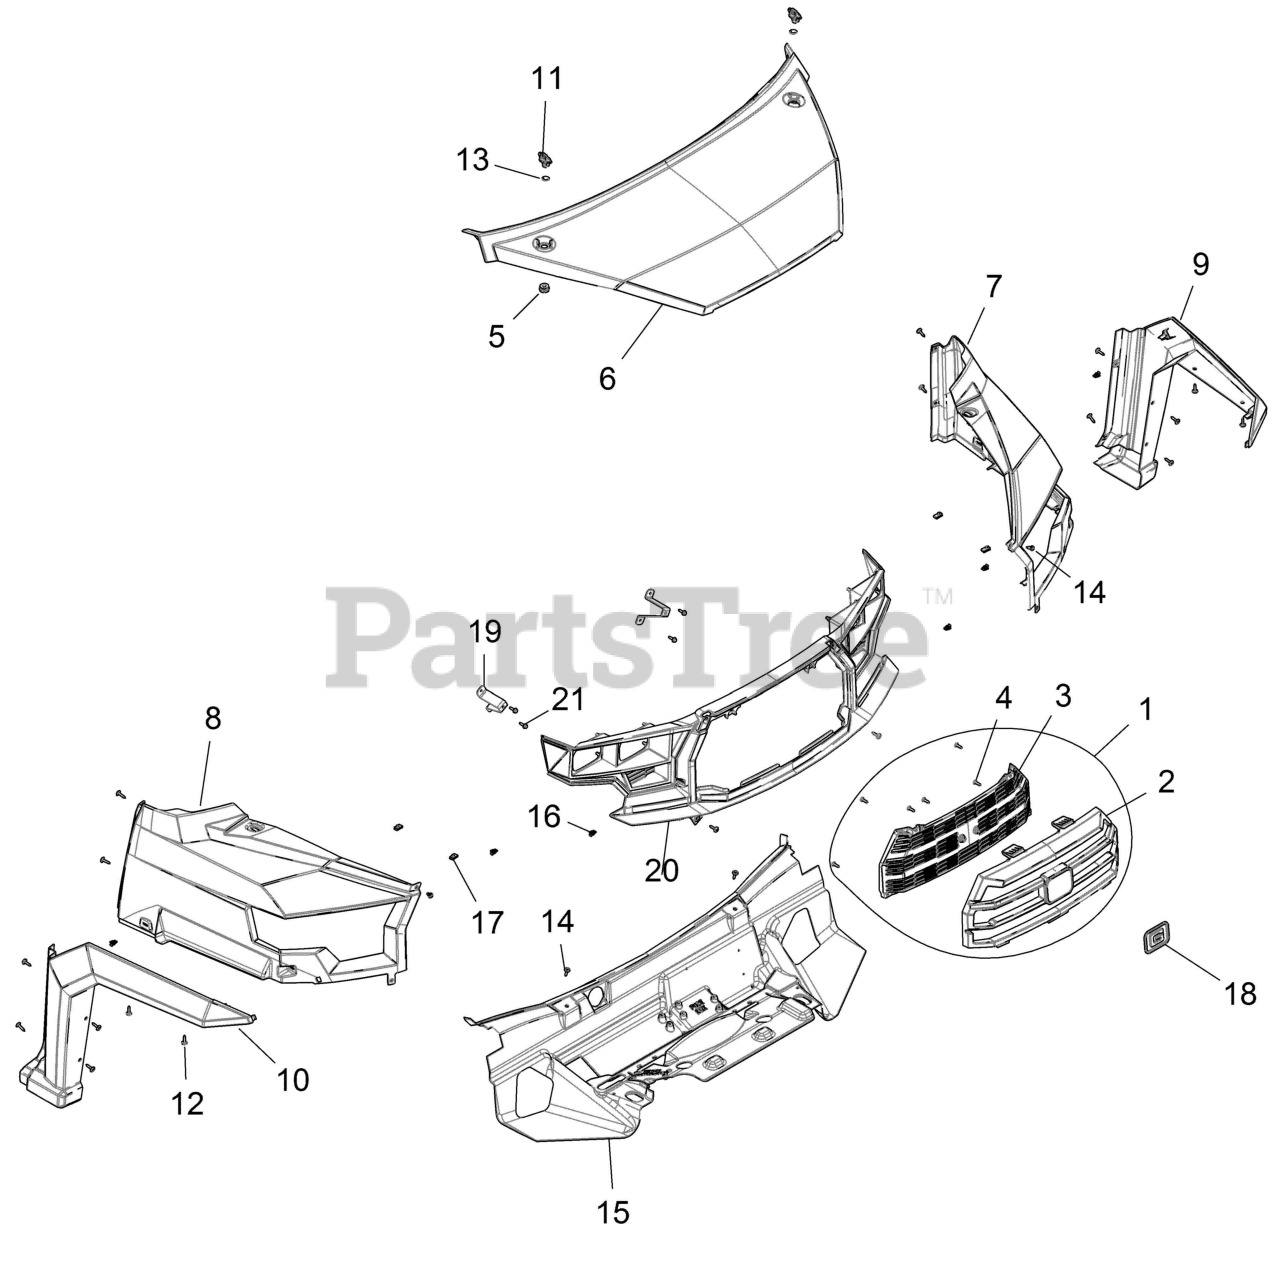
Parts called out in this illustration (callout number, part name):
1	ASM., GRILL, GRAVELY
2	GRILL, FRONT, UPPER, BLACK
3	GRILL, UPPER, TRIM
4	SCR-TXPH-#14 X .75 HI-LO RIE
5	GROMMET-LATCH
6	HOOD-ARIENS,INDY RED
7	FENDER-FRONT,LH,ARIENS,I RED
8	FENDER-FRONT,RH,ARIENS,I RED
9	FLARE, FENDER, FRONT LH
10	FLARE, FENDER, FRONT RH
11	LATCH, 1/4 TURN
12	SCR-TXTH-M6X1.0X25 RIE
14	RIVET-TUFLOK,.315-.325X.787 (5
15	LINER-HOOD,BLK
16	CLIP, DASH TRIM METAL
17	CLIP-U SPEED NUT
19	BRKT-FASCIA MOUNT
20	BEZEL-HEADLIGHT
21	SCR-M6X1.0X20,HXHD,FLG,TDFM,BL
